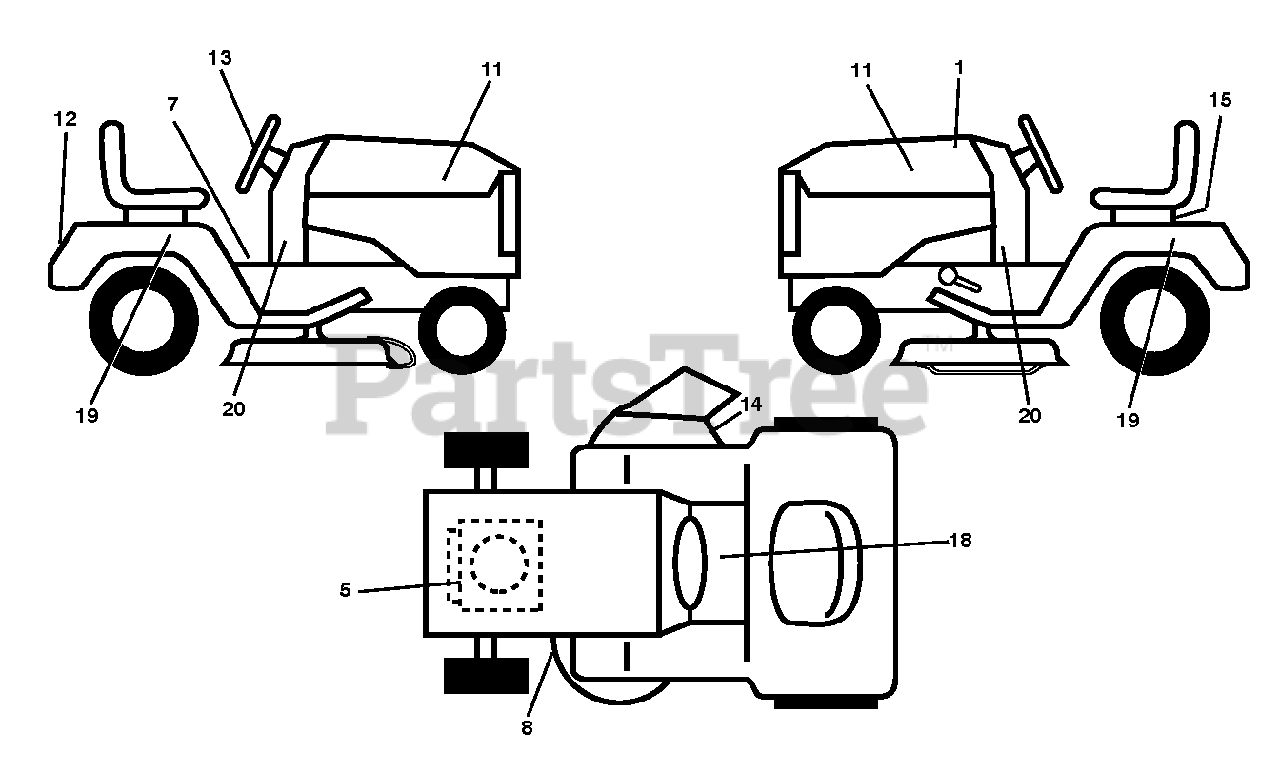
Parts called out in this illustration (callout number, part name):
7	Fender Engine Warning Decal
11	DECAL.HOOD.ALPHA.RH/LH.POULAN
11	DECAL HANDLE LIFT
12	DECAL.FEND.POULAN.2010
13	DECAL.WHEEL.STEER.STD.MCCULLOC
14	DECAL.WARN.KEEP.HAND.AWAY
15	DECAL BTRY SYMBOLS
19	DECAL.FEND.RH/LH.SET.6S.POULAN
